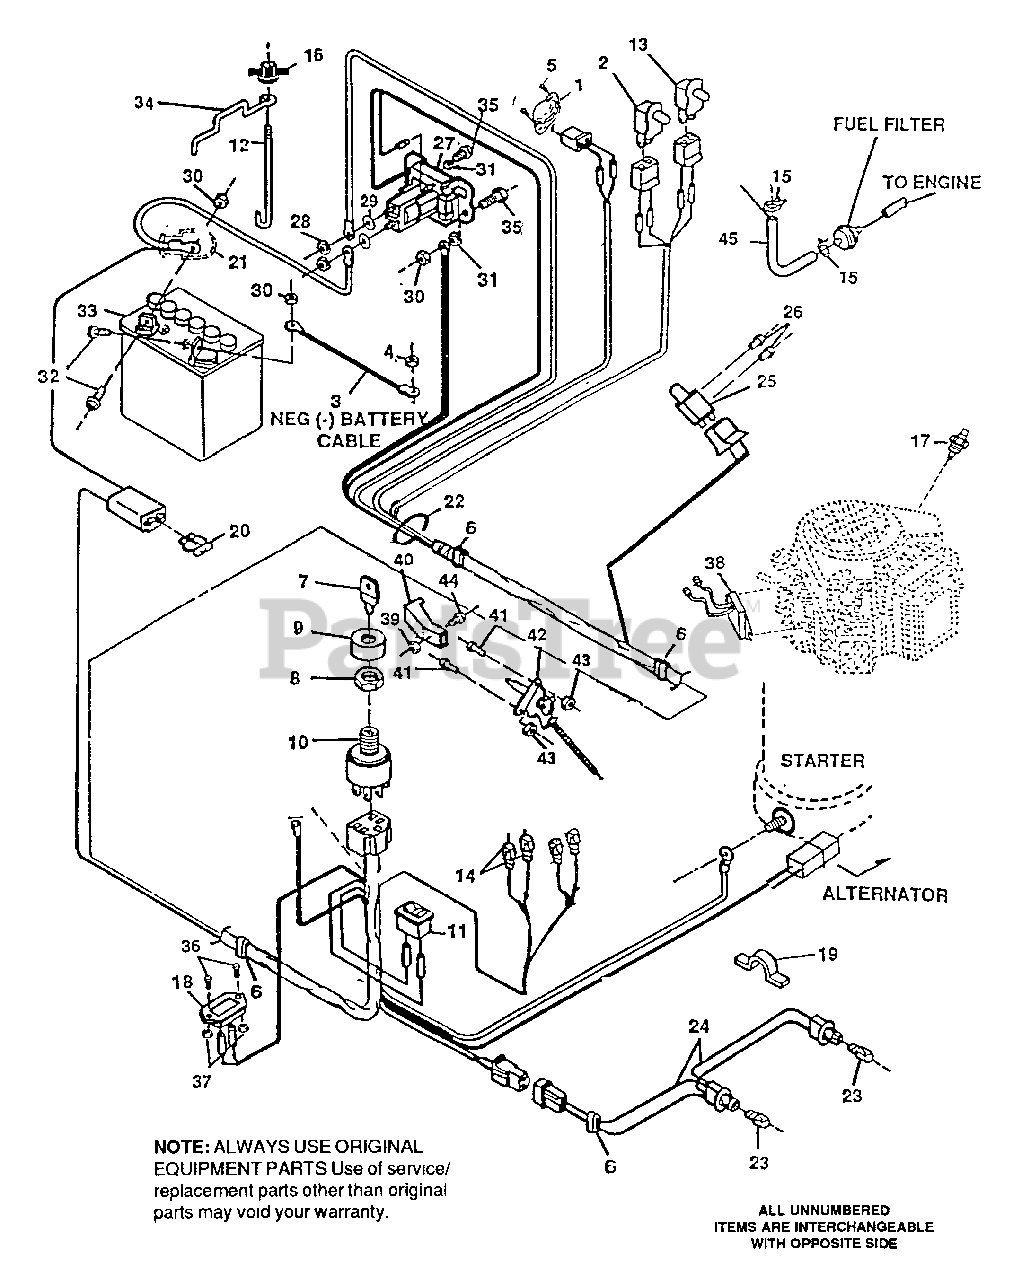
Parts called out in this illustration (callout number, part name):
1	Seat Switch
2	Switch, Snap Mnt No. .140 Blue
3	Cable, Battery, Negative
4	Nut, Hx, Keps, 5/16-18 Thd.
5	Screw, 1/4-20 x .38
7	Key, Ignition Switch
8	Nut, Switch
9	Boot, Switch
10	Switch, Ignition
11	Switch, Light
12	Rod, Battery Hold-Down
13	Switch, Snap Mnt No. .140 Wh.
14	Bulb, Indicator
15	Clamp, Gas Line
17	Oil Sensor
18	Minature Hour Meter
19	Press Clip
20	Fuse, 15A-32V, Spade Type
21	Boot, Rubber (Battery Cable)
22	Wire Harness
23	Bulb Headlamp
24	Assembly, Light Wire
26	Screw, Pn Hd, Tap #12 x 1/2 In.
28	Nut, Hx 5/16-24 Thd.
29	Washer, Lock 5/16 In.
30	Nut, Hx, Keps, 1/4-20 Thd.
31	Nut, Hx, Ctrlk, 1/4-20 Thd.
32	Screw, 1/4-20 x 5/8 In.
34	Bracket, Battery Hold-Down
35	Screw, 1/4-20 x 3/4 In.
36	Screw, #6-32 x .50
37	Nut, Hx Keps 6-32
38	Regulator, Sen. Volt BS with Sensor
39	Nut, Hex #8-32 Thd.
40	Knob, Throttle Control
41	Screw #10-24 x 5/8
42	Throttle Control
43	Nut, Hex, Nylon Lock #8-32 x 3/8 In.
44	Screw,Ph, Pn, #8-32 x 3/8 In.
